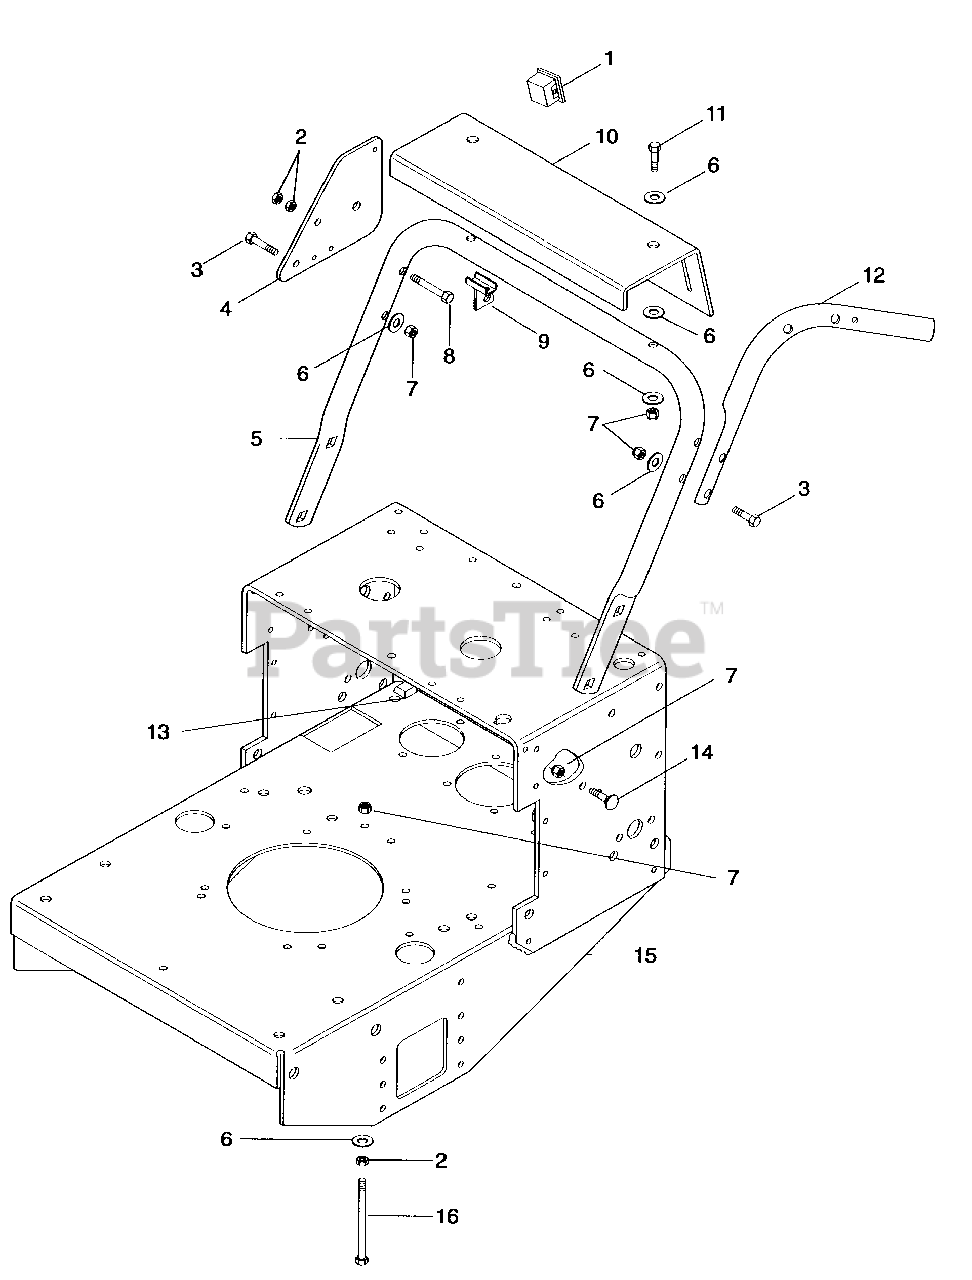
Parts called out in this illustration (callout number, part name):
1	Switch, Blank
2	Nut, Hex .375-16
3	Bolt, Hex, .38-16 x 2.25, Grade 5
4	Plate, Speed Control Lever
5	Tube, Handlebar Mounting
6	Washer, Flat, Steel .406 x .812 x .065
7	Nut, Locking, Nylon .375-16
8	Bolt, Hex .38-16 x 2.50 Grade 5
9	Weldment, PTO Lever Mounting
10	Panel, Instrument
11	Bolt-Hex .38-16 x 2.00 Grade 5
12	Handlebar, Left Hand
13	Stop
14	Bolt, Round Head Square Neck .38-16 x 1.0
15	Weldment, Frame
16	Bolt, Hex .38-16 x 4.00
